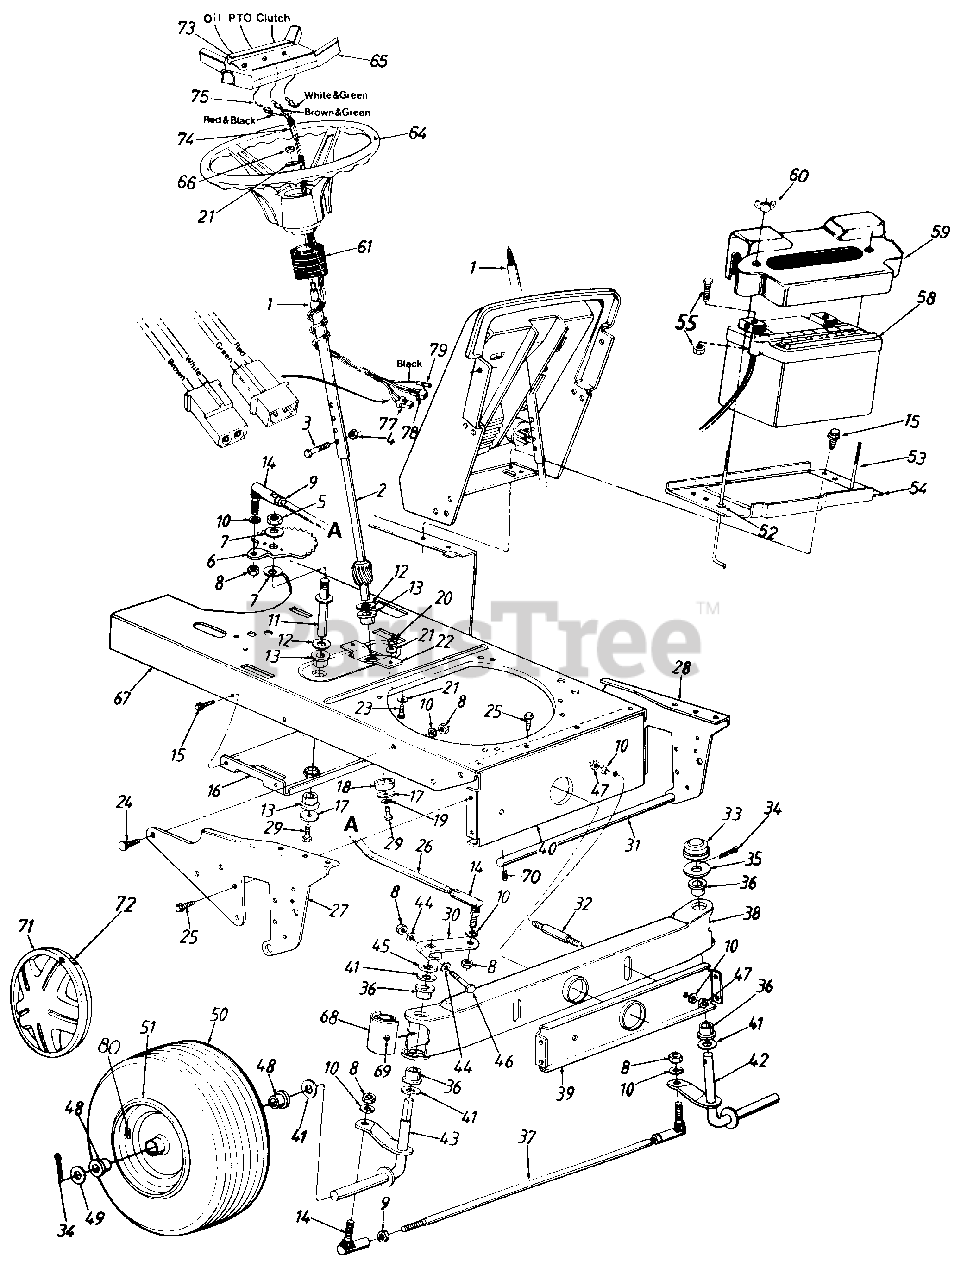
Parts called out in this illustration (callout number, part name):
1	Steering Column Ass'y.
2	Lower Steering Shaft
3	Hex Bolt 1/4-20 x 1.31" Lg.
4	Hex L-Nut 1/4-20 Thd.
5	Hex Nut 5/8-18 Thd.
6	Steering Gear Segment
7	Bell-Wash. 5/8" I.D. x 1.25" O.D.
8	Hex Nut 3/8-24 Thd.
9	Hex Jam Nut 3/8-24 Thd.
10	L-Wash. 3/8" I.D.
11	Steering Gear Segment Shaft
12	Fl-Wash. .64" I.D. x 1.24" O.D.
13	Hex Flange Brg. .63" I.D.
14	Ball Joint Ass'y.
15	Hex Wash. Hd. TT-Tap Scr. 1/4-20 x .5" Lg.
16	Deck Idler Support Brkt.
17	Fl-Wash. .33" I.D. x 1.25" O.D.
18	Spacer .985" I.D. x 1.25" O.D.
19	L-Wash. 5/16" I.D.
20	Hex Nut 5/16-24 Thd.
21	Bell-Wash. .345" I.D. x .88" O.D
24	Ribbed Neck Bolt 3/8-24 x .8" Lg.
25	Hex Wash. TT-Tap Scr. 5/16-18 x .62" Lg.
26	Steering Drag Link
27	Pivot Bar Side Plate R.H.
28	Pivot Bar Side Plate L.H.
29	Hex Bolt 5/16-18 x .62" Lg.
30	Steering Arm
31	Deck Connecting Rod
32	Pivot Bar Shld. Bolt 3/8-16 x 518" Lg.
33	Cap
34	Cotter Pin 5/32" Dia.
35	Flat Washer
36	Flange Brg. .757" I.D.
37	Tie Rod 20.25" Lg.
38	Pivot Bar Assy.
41	Fl-Wash. .76" I.D. x 1.49" O.D.
42	Front Axle Ass'y. L.H.
43	Front Axle Ass'y. R.H.
44	Bowed Washer
45	Spacer .755" I.D. x 1.25" O.D.
46	Hex Bolt 3/8-24 x 2.25" Lg.
47	Hex Nut 3/8-16 Thd.
48	Needle Brg. .75" I.D.
49	Fl-Wash. .71" I.D. x 1.5" O.D.
50	Wheel Ass'y. Comp.
51	Rim Only
52	Push Nut
53	Battery Hold Down Rod
54	Battery Support Brkt.
55	Comes w/Battery
58	Battery (275 Cold Crank Amps)
59	Battery Cover
60	Wing Nut Plastic 1/4-20 Thd.
61	Steering Bellow
64	Steering Wheel
65	Steering Wheel Insert
66	Hex L-Nut 5/16-24 Thd.
67	Lower Frame
68	Pivot Bar End Cap
69	Grease Fitting
70	Internal Cotter Pin
71	Hub Cap
72	Spring Clip
73	Steering Wheel Insert Label
74	Wire Harness
75	Bulb
77	Connector
78	Connector
79	Connector
80	Air Valve
